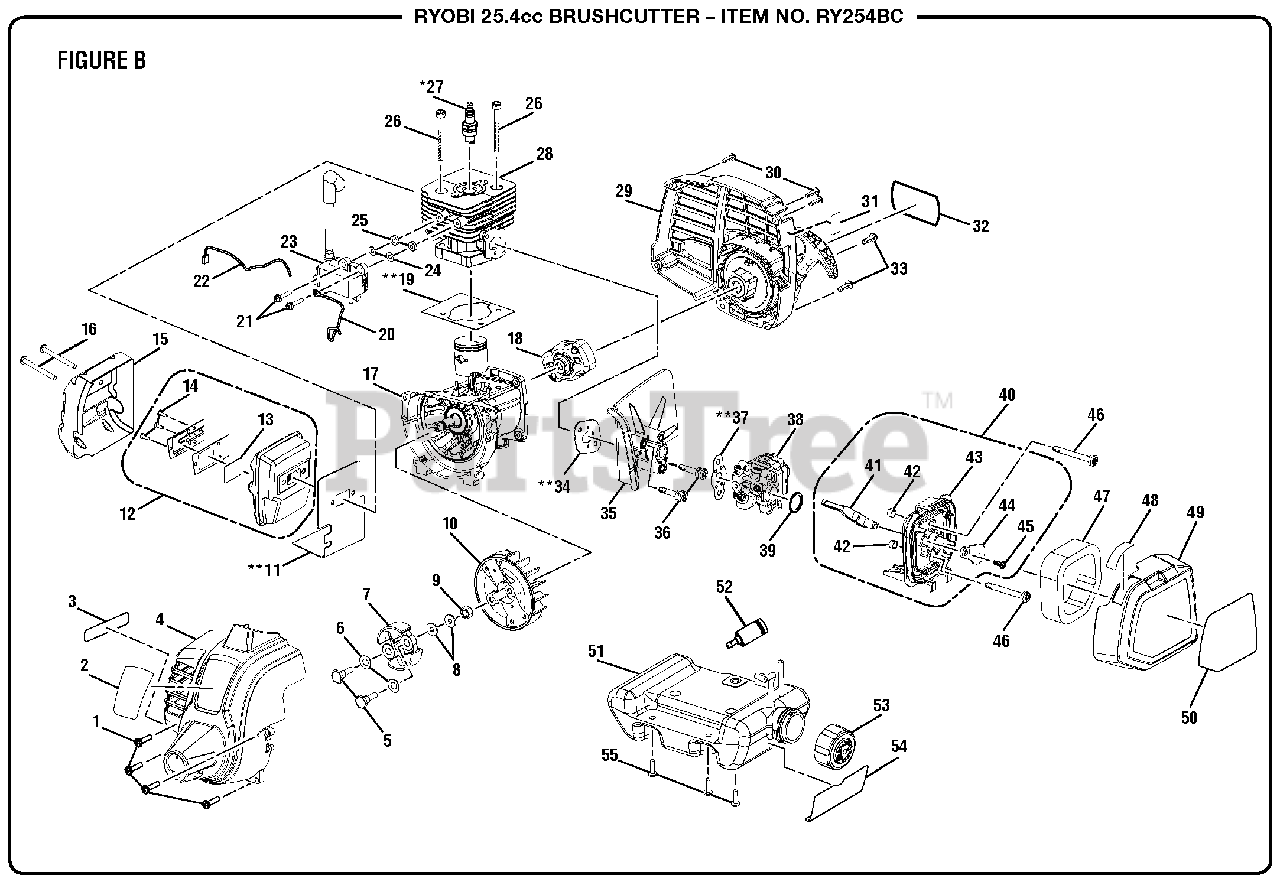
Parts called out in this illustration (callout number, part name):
1	Screw w/Washer (M5 x 20 mm, T20 Torx Pan Hd)
2	Logo Label (Front)
3	Combustion Warning Label
4	Front Housing Assembly
5	Clutch Shoulder Bolt (M6 x 225 mm, Hex Hd)
6	Curved Washer
7	Clutch Assembly
8	Washer (ID6 x OD15 x 12t)
9	Flywheel Nut
11	Muffler Gasket
12	Muffler Assembly
13	Screen
14	Screw (6-20 x 1/4 in, T20 Torx Pan Hd)
15	Heat Shield
16	Screw (M5 x 50 mm, T25 Torx Pan Hd)
17	Crankcase Assembly
18	Starter Cup
19	Gasket
20	Lead Wire (Red)
21	Screw w/Washer (M4 x 19 mm, T20 Torx Pan Hd ST)
22	Lead Wire (Black)
23	Coil Boot Assembly
24	Washer (ID42 x OD10 x 1t)
25	Spacer (Phenolic)
26	Screw (M5 x 22 mm, Soc Hd)
27	Spark Plug (Champion RCJ4)
29	Rear Housing and Starter Assembly
30	Screw (M4 x 18 mm, T20 Torx Pan Hd. S.T.)
31	Primer Bulb Location Label
32	Logo Label (Rear)
33	Cap Screw w/Washer (M5 x 16 mm, T25 Torx Soc Hd)
34	Insulator Gasket
35	Heat Dam Insulator
36	Screw (M5 x 27 mm, T25 Torx Pan Hd ST)
37	Gasket
38	Carburetor Assembly
39	Carburetor O-Ring
40	Airbox Base Assembly
41	Choke Lever
42	Compression Limiters
43	Air Box Base
44	Choke Plate
45	Screw (M4 x 12 mm, T20 Torx Pan Hd ST)
46	Screw (M5 x 44 mm, T20 Torx Pan Hd)
47	Air Filter
48	Choke Position Label
49	Airbox Cover
50	Starting Instructions Label
51	Fuel Tank and Cap Assembly
52	Fuel Filter
53	Fuel Cap Assembly
54	Fuel Mixture Label
55	Shoulder Screw (M4 x 14 mm, T25 Torx Truss Hd ST)
